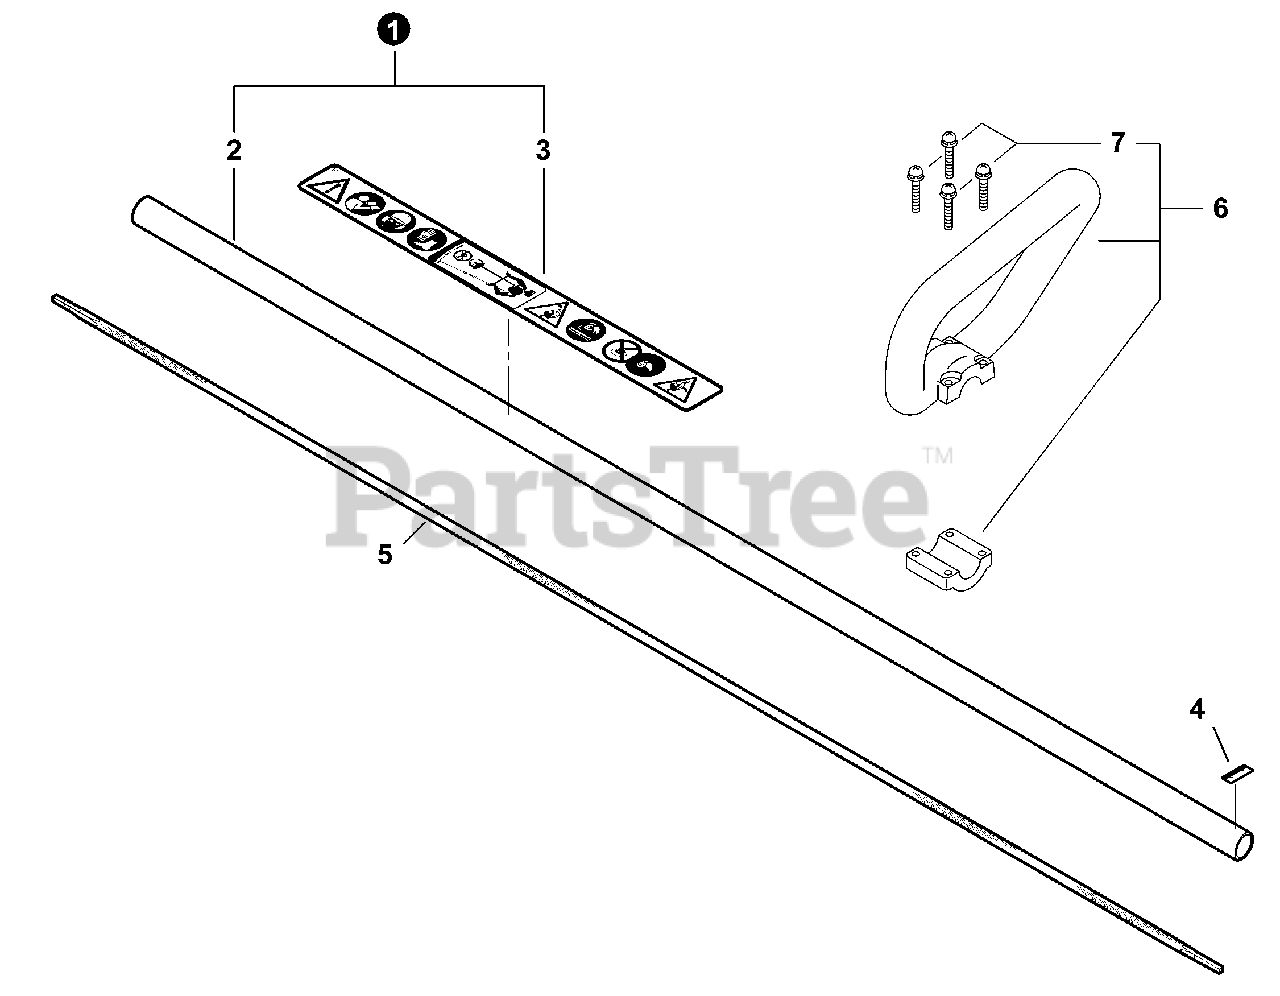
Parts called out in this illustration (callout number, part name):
1	MAIN PIPE ASSY
2	MAIN PIPE ASSY 25x1500
3	LABEL - CAUTION - ISO
4	LABEL - ALIGNMENT
5	DRIVESHAFT - FLEXIBLE L= 1522
6	HANDLE ASSY - LOOP
7	SCREW 5x35
